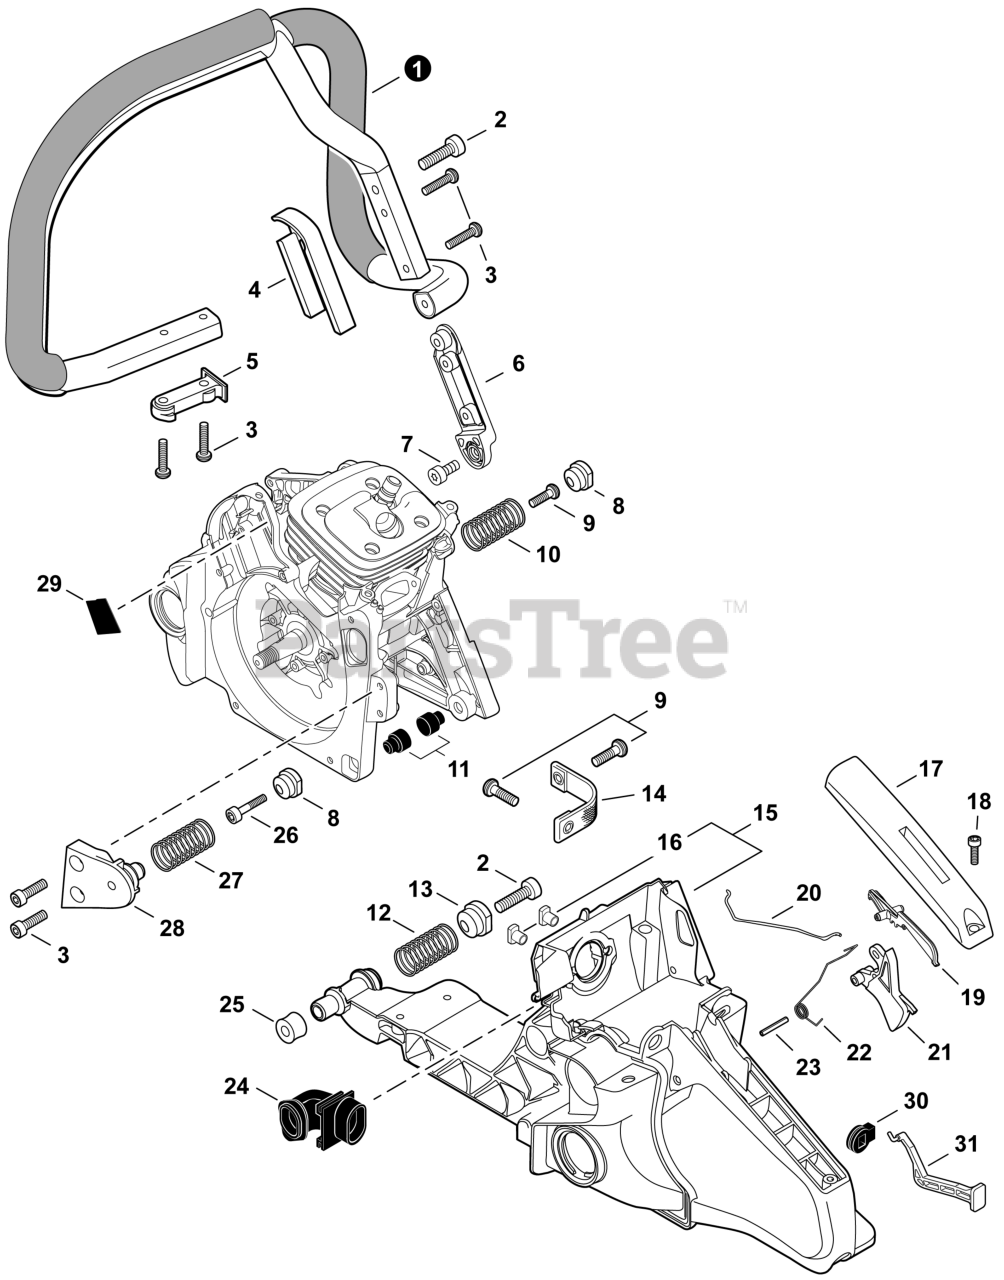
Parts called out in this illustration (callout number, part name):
1	HANDLE, FRONT
2	BOLT, TORX 6x20
3	BOLT, TORX 5x20
4	HOLDER, SPRING
5	MOUNT, HANDLE
6	BRACKET, HANDLE
7	BOLT, TORX 5x16
8	HOLDER, SPRING 14.4
9	BOLT, TORX 5x16
10	SPRING, COMPRESSION 17x38.4x2.6
11	CUSHION
12	SPRING, COMPRESSION 20x40x3.3
13	HOLDER, SPRING 17
14	STRAP, SAFETY
15	HANDLE, REAR
16	NUT M5
17	COVER, HANDLE
18	BOLT, TORX 4x12
19	LEVER, THROTTLE LOCKOUT
20	ROD, THROTTLE
21	TRIGGER, THROTTLE
22	SPRING, TORSION
23	PIN, SPRING 4x25 SUS
24	PIPE, AIR INTAKE
25	CUSHION 10
26	BOLT, TORX 5x25
27	SPRING, COMPRESSION 17x36.7x2.6
28	HOLDER, SPRING
29	CUSHION
30	GROMMET, CHOKE
31	ROD, CHOKE
